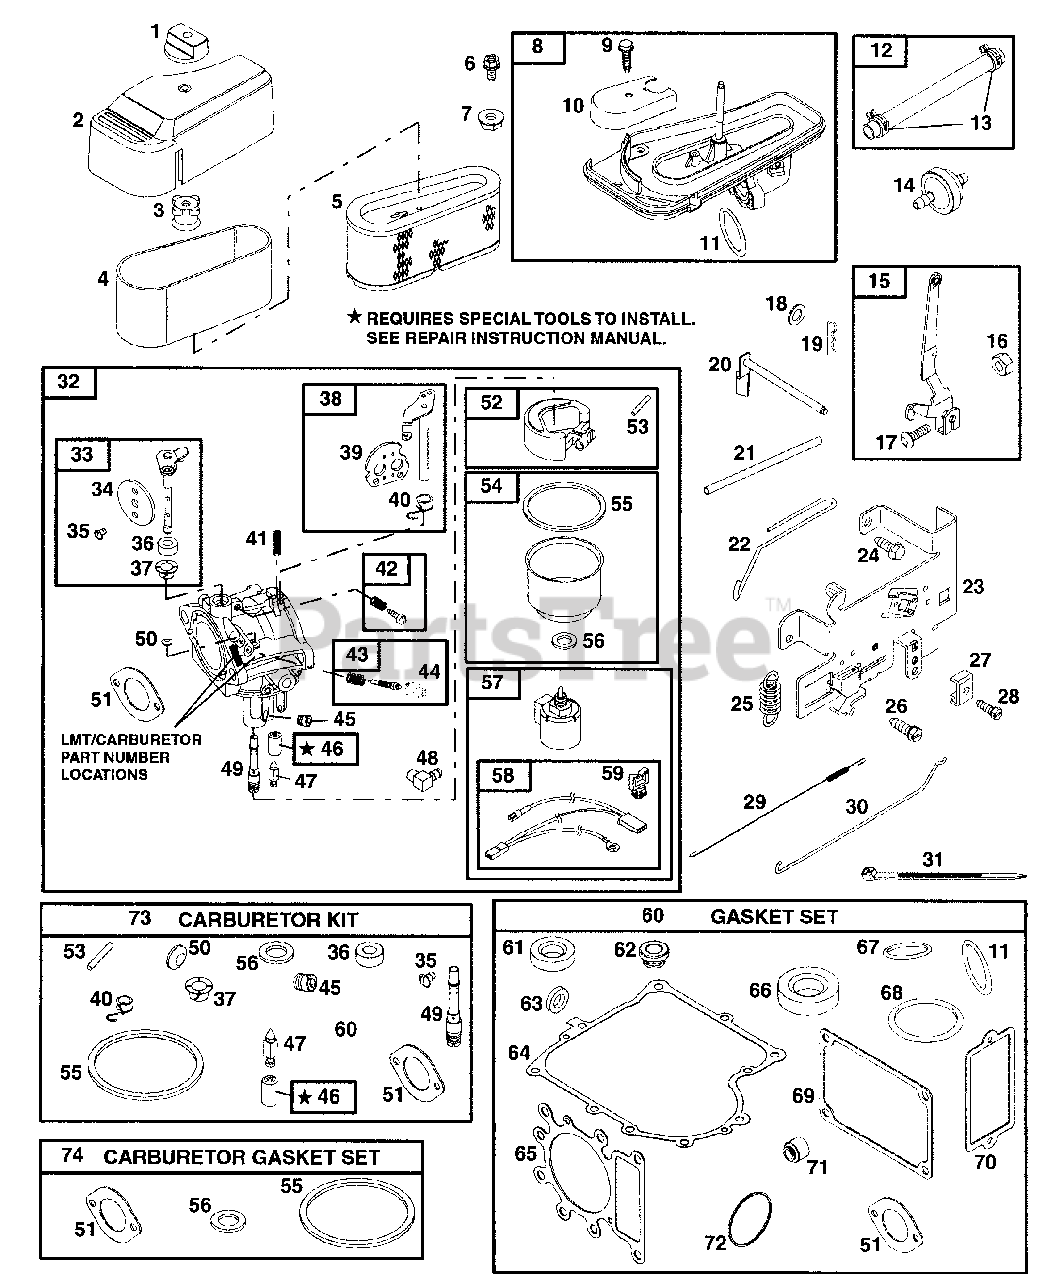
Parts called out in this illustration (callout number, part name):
1	Knob (Air Cleaner)
2	Air Cleaner Cover
3	Air Cleaner Stud Seal
4	Pre-Cleaner Filter
5	Air Cleaner Filter Cartridge
6	Screw (Air Cleaner Base)
7	Nut (Air Cleaner Brace)
8	Air Cleaner Base
9	Screw (Carburetor Shield)
10	Carburetor Shield
11	O-Ring Seal (Air Cleaner Base)
12	Fuel Line Cut to Required Length
13	Hose Clamp
14	Fuel Filter
15	Governor Control Lever
16	Nut (Governor Lever)
17	Bolt (Governor Lever)
18	Washer (Governor Crank)
19	Cotter Pin
20	Governor Crank
21	Cable Shield
22	Choke Link
23	Control Bracket
24	Screw (Control Bracket)
25	Governor Spring
26	Screw (Remote Choke Stop)
27	Casing Clamp
28	Screw (Casing Clamp)
29	Spring (Governor Link Spring)
30	Mechanical Governor Link
32	Carburetor
33	Throttle Shaft
34	Throttle Valve
35	Screw (Throttle Valve)
36	Throttle Shaft Seal
37	Throttle Shaft Bushing
38	Choke Shaft (Remote)
39	Choke Valve (Remote)
40	Spring & Seal Assembly
41	Friction Spring
42	Idle Speed Kit
43	Idle Mixture Kit
44	Limiter Cap
45	Main Jet (Standard)
46	Inlet Seat
47	Inlet Needle Valve
48	Fuel Pipe Elbow
49	Carburetor Nozzle
50	Welch Plug (Sold in Kit Only)
51	Intake Gasket
52	Carburetor Float
53	Float Hinge Pin
54	Float Bowl
55	Float Bowl Gasket
56	Sealing Washer
57	Fuel Solenoid
58	Wiring Harness
60	Gasket Set
61	Oil Seal
62	Dipstick Tube Seal
63	Governor Shaft Seal
64	Crankcase Gasket .015" Thick
65	Cylinder Head Gasket
66	Oil Seal
67	O-Ring Seal (Dipstick)
68	O-Ring Seal (Oil Pump Cover)
69	Rocker Cover Gasket
70	Breather Gasket
71	Valve Seal
72	O-Ring Seal (Intake Manifold)
73	Carburetor Kit
74	Carburetor Gasket Set
